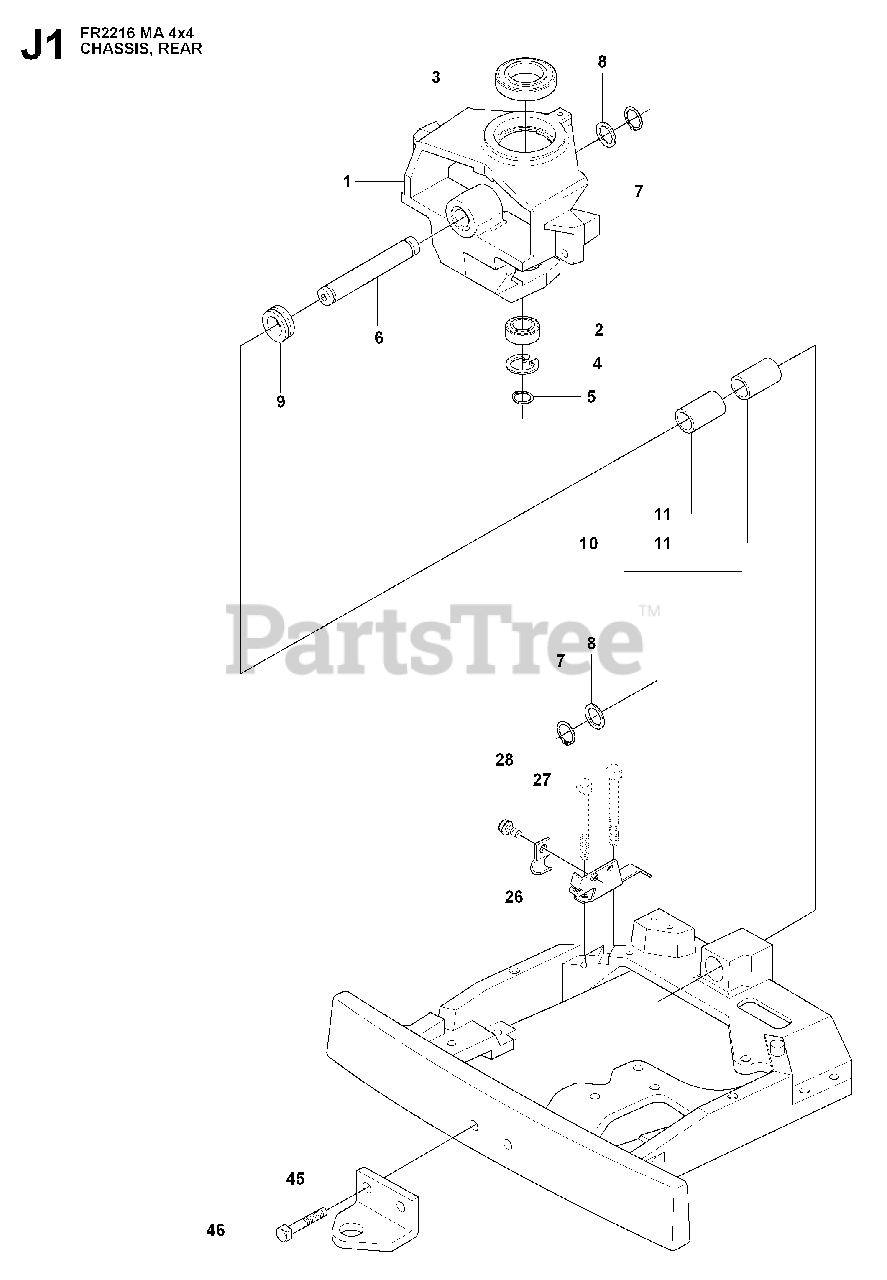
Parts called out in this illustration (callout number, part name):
2	BALL BEARING 6005-2RS
3	BALL BEARING 6010 2RS1
4	CIRCLIP SGH 47
5	RETAINING RING SGA 25
7	RETAINING RING SGA 25
45	DRAW RING
46	SCREW M10X25
